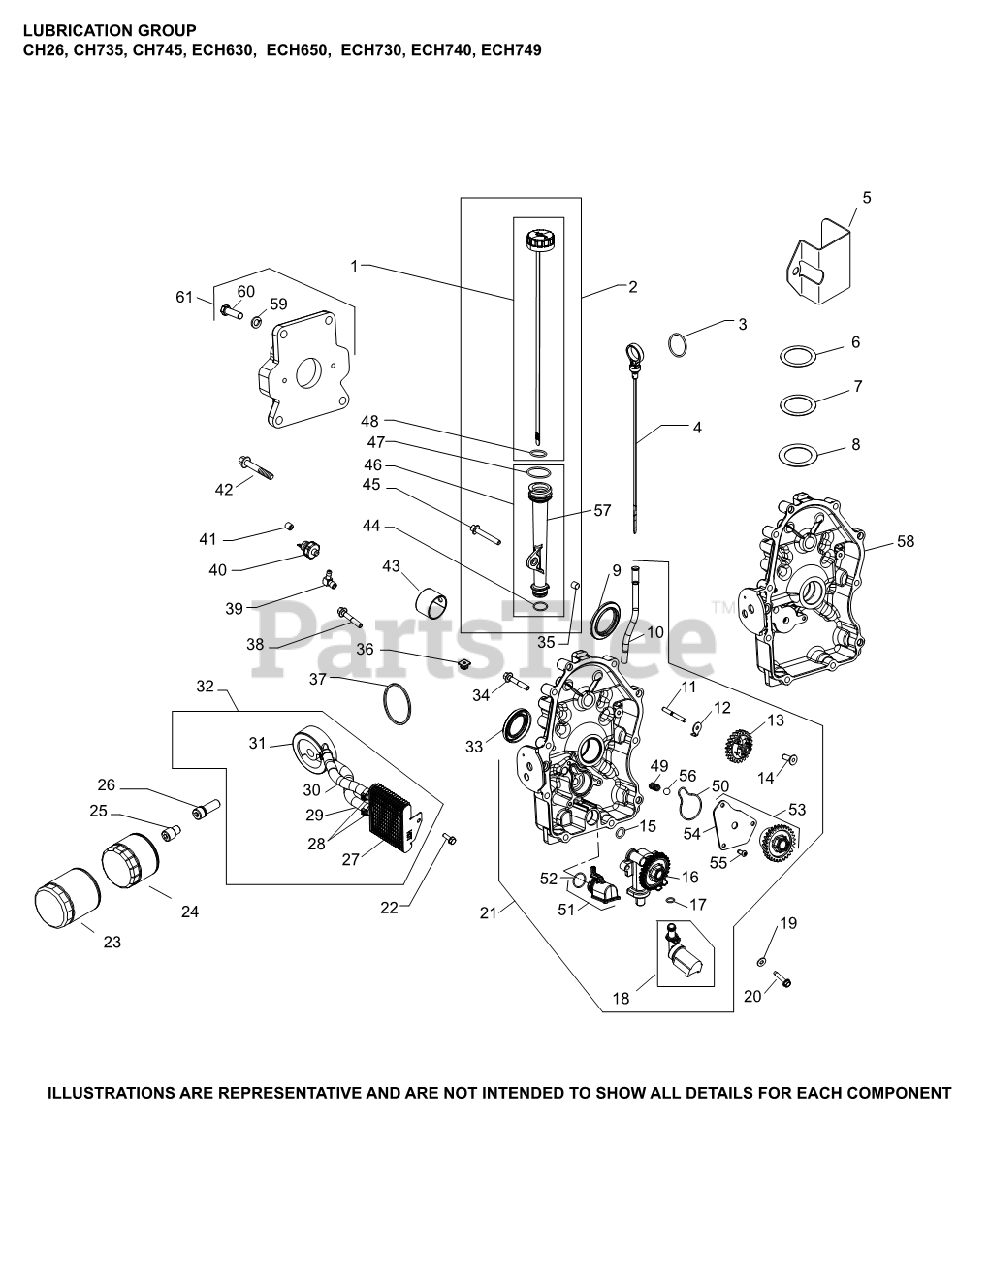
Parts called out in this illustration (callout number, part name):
10	KIT, DIPSTICK/DIPSTICK TUBES
11	SHAFT, GOVERNOR GEAR
12	TAB, LOCKING
13	KIT, GOVERNOR GEAR W/PIN
14	PIN, GOVERNOR REGULATING
16	KIT, OIL PUMP ASSEMBLY
17	O-RING, OIL PICK-UP
18	PICK-UP, OIL
19	WASHER, FLAT 1/4" (O.D. 5/8")
20	SCREW, THREAD FORMING
21	CLOSURE PLATE ASSEMBLY USE 24 009 211-S
22	SCREW, TAP M6X1.7X18
23	OIL FILTER
26	NIPPLE, OIL FILTER
27	COOLER, OIL ASSEMBLY
28	CLAMP, HOSE LOW PROFILE
29	HOSE, OIL COOLER
30	HOSE, OIL COOLER
31	ADAPTER, OIL FILTER (CH EFI)
32	COOLER, OIL & DIVERTER ASSEMBLY USE 24 594 58-S
33	SEAL, OIL
34	SCREW - DISCONTINUED
36	NUT, PLASTIC - BLACK
37	O-RING, OIL COOLER
38	SCREW, FLG M8X1.25X45
40	SENSOR, OIL PSI
49	SPRING, COMPRESSION
50	SEAL, OIL PUMP COVER
51	PICK-UP ASSEMBLY, OIL
52	O-RING, OIL PICK-UP
53	PUMP ASSEMBLY, OIL
54	COVER, OIL PUMP
55	SCREW, BUTTON HEAD
56	PRESSURE RELIEF BALL
